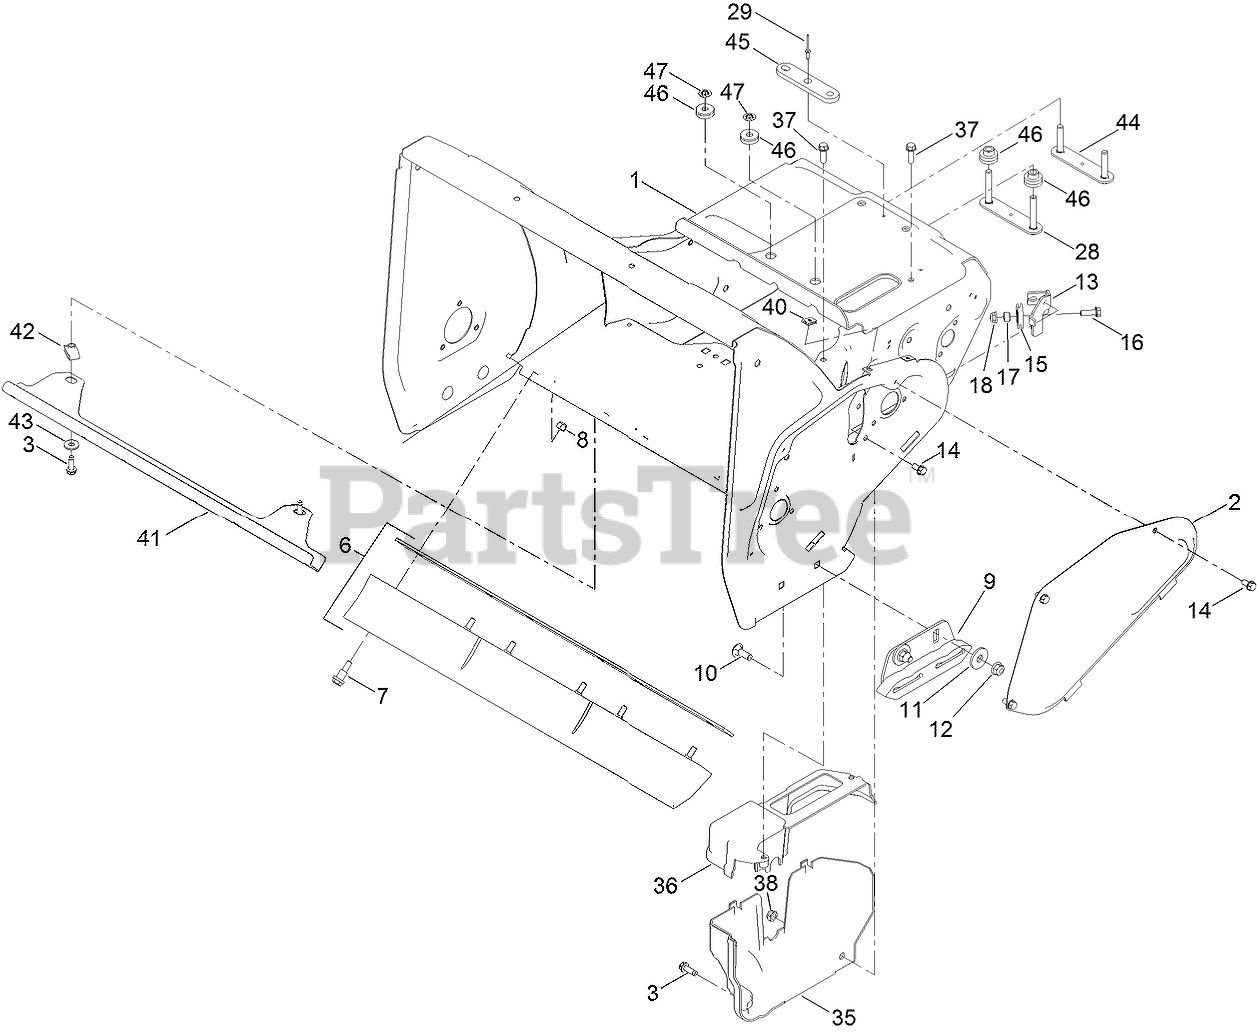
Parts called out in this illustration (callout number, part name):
2	COVER-BELT
3	SCREW-HWHTF
6	SCRAPER ASM
7	BOLT-SHOULDER
8	NUT-LOCK, NI
9	SKID ASM
10	SCREW-CARR
11	WASHER
12	NUT-HF, NI
13	BRACKET-CABLE
14	SCREW-HWH
15	CABLE-PULLEY
16	SCREW-HHF
17	SPACER-BLADE, ROTOR
18	NUT-HF
28	PLATE-STUD, FRONT
29	RIVET
35	COVER-BELT, LOWER
36	COVER-BELT, UPPER
37	SCREW-HWH
38	NUT-LOCK, NI
40	NUT-SPEED
41	SUPPORT-FRAME, LOWER
43	WASHER-FLAT
44	PLATE-STUD, REAR
45	PLATE-SPACER
46	ISOLATOR-ENGINE
47	RING-RETAINING, BOLT
